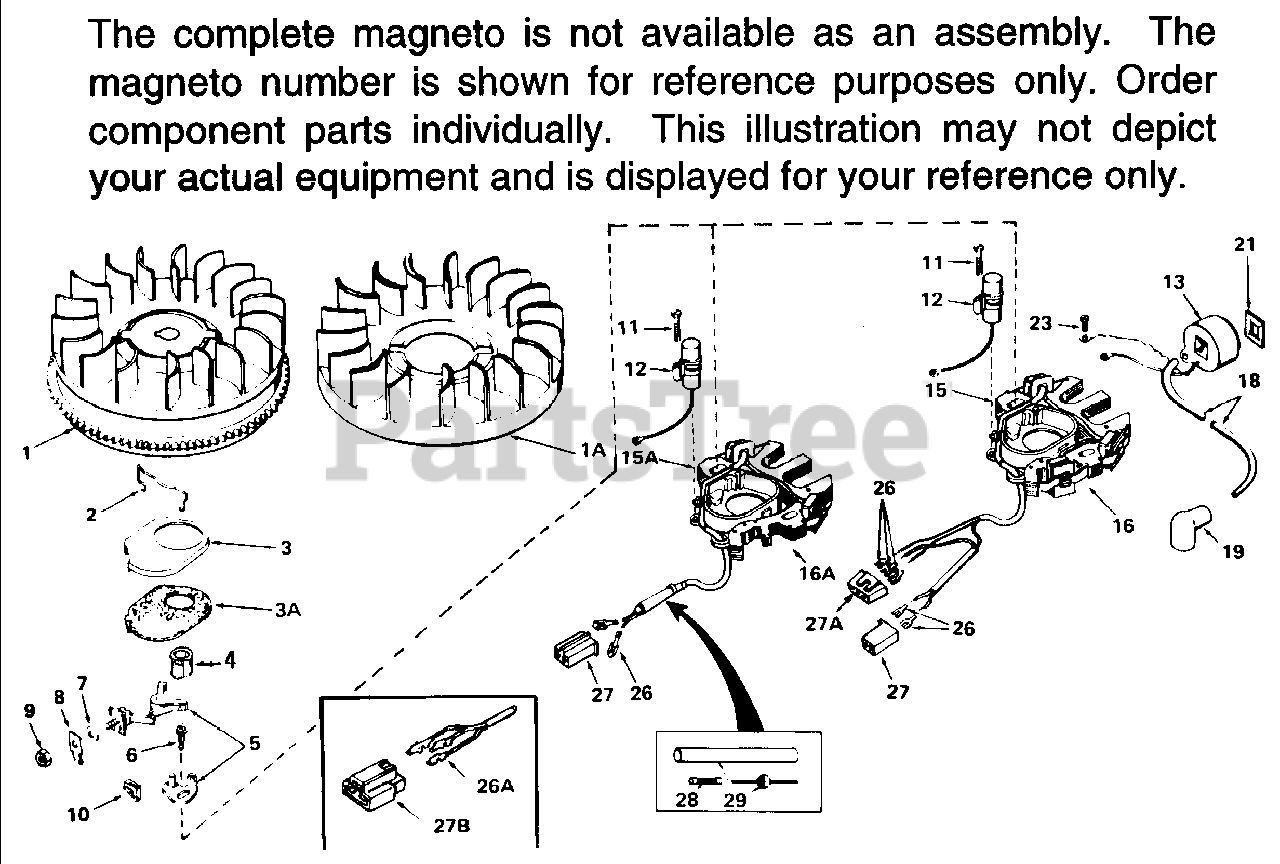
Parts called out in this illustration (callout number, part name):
1	Flywheel (Incl. 1A)
2	Spring, Dust cover
3A	Cover, Dust
4	Cam, Breaker
5	Breaker Points (also available in Pac kaged Part #740037B)
6	Screw & Lockwasher
7	Washer, Terminal
8	Tab, Terminal
9	Nut, Terminal
10	Felt, Cam wiper
11	Screw, Condenser fastener
12	Condenser (also available in Packaged Part #740037B)
13	Coil (Incl. 18)
14	Spring, Coil wedge
15	Stator Plate Assy. Incl. 2, 3, 3A, 5 thru 14, 16 thru 23, 32, 32A, 33, 36 & 37
16	Core & Plate Group
17	Generating Coil & Leads (2 Circuit) ( Incl. 36 & 37)
18	Wire, Lead
19	Sleeve, Insulation
20	Shield, Coil
21	Clip, Coil fastening
22	Clip, Ground
23	Screw, Ground terminal
32A	Gasket, Dust cover (23/32 Hole)
33	Clip, Coil locking
36	Terminal, Male
37	Connector, Pyramid
